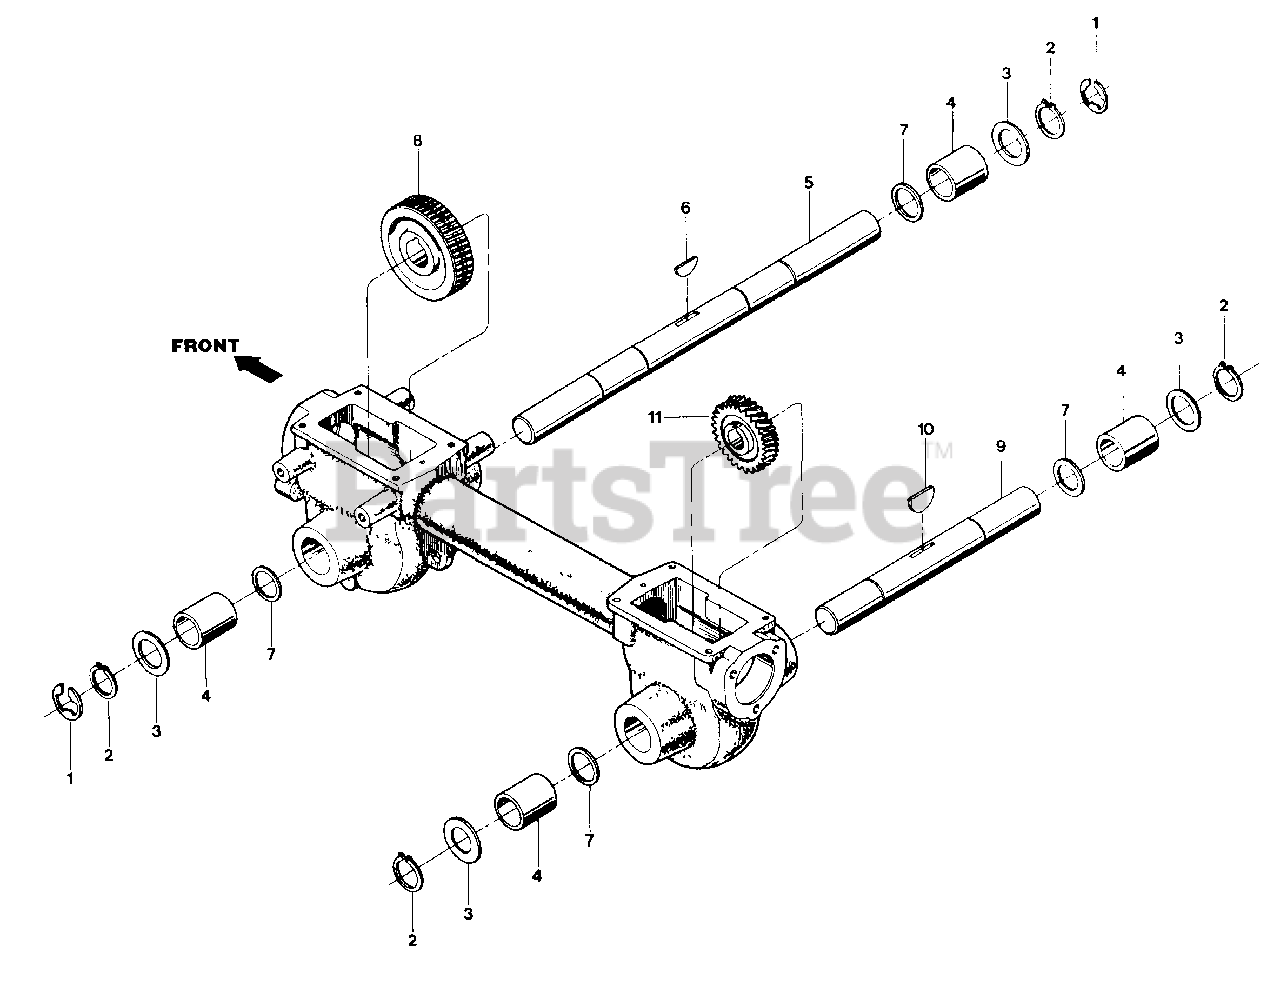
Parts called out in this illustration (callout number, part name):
1	Retainer - Snap Ring, "E" Type
2	Retainer - Snap Ring
3	Shim 0.062" Thick
4	Bushing-Bronze
5	Wheel Shaft
6	Key - Wheel Shaft, Hi Pro, 1/4 x 1
7	Spacer
8	Worm Gear - Wheel Shaft
9	Tiller Shaft
10	Woodruff Key - Tiller Shaft
11	Worm Gear - Tiller Shaft
